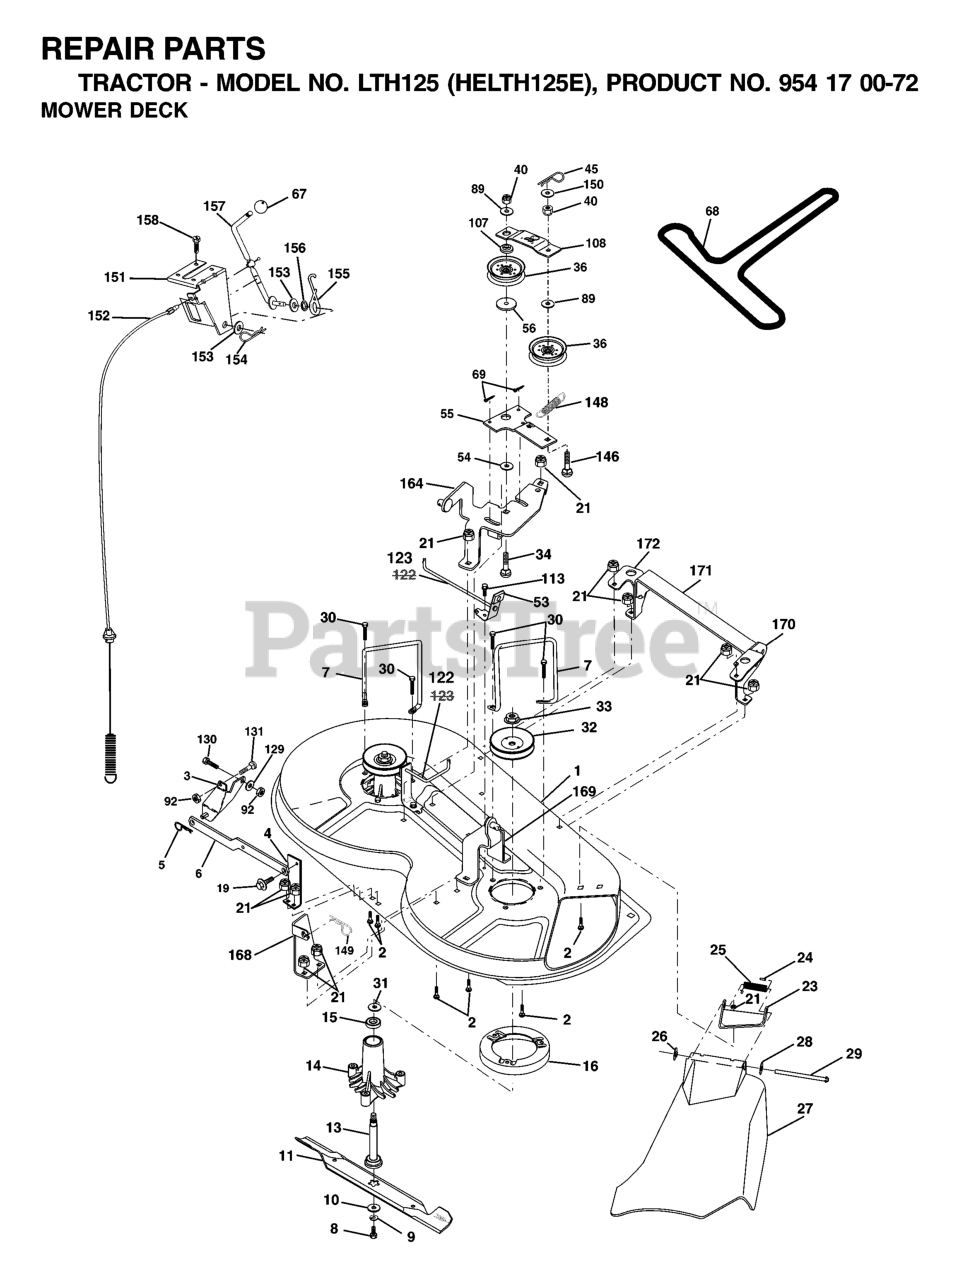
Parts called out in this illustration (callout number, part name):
2	RP BOLT 5/16-18 X3/4 ZN/YEL GR
3	BRKT ASM SWAY BAR
5	RETAINER-SPRNG RB
6	BAR SWAY DECK
8	BLADE BOLT
9	LOCKWASHER
10	WASHER.BLADE
11	BLADE, HI-LIFT 36" PREMIUM
13	SHAFT ASM VENT
14	HOUSING.MANDREL.VENTED (MACHD)
16	STRIPPER.MANDREL.ROUND.BLACK
19	BOLT SHD 5/16-18
21	LOCKNUT
23	BRACKET ASM DEFLECTOR
24	CAP-SLEEVE LT
25	SPRING TORSION
26	NUT PUSH M
27	CONSOLE.STLT.5SP.BLK
28	Washer 11/32 x 5/8 x 16 Ga SD
29	HINGE ROD
30	SCREW, WASHER HEAD
31	WASHER
32	PULLEY, MANDREL
33	NUT, FLG TOPLOCK 9/16"
36	FLAT IDLER PULLEY
45	RETAINER M
53	BRAKE ASSEMBLY
54	HARDENED WASHER
56	SPACER.RETAINER.MOWER
67	KNOB T (3/8 HOLE)
68	V-BELT.MOWER.
69	COTTER PIN
89	WASHER GT
92	NUT
107	SPACER.IDLER.ARM
108	STIFFENER.IDLER.ARM
113	Screw 5/16-18 x 1/2 Hex, Self Tapping 5/16-18 x 1/2
129	WASHER
131	BOLT D
146	BOLT, CARRIAGE IDLER
148	IDLER RETURN SPRING
149	SPRING.RETAINER.YELLOW.ZINC
151	BRACKET.CLUTCH.CABLE
153	WASHER FLAT 3/8"
154	SPRING RETAINER
155	SPRING RETENTION LEVER
156	SPACER.CLUTCH.CABLE
157	ROD CLUTCH CABLE 3/8"
158	SCREW
171	BRACE.SUPT.SUSP.FRT.CRD
